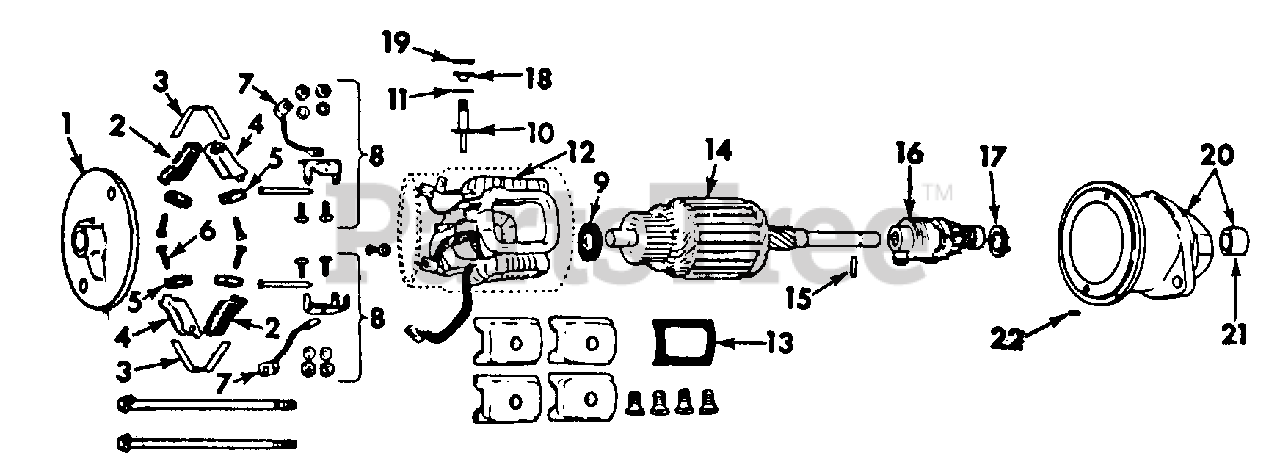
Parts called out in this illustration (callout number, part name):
1	MOTOR ASSY, CRANKING IH-131174-C91
1	FRAME, COMMUTATOR END
2	HOLDER, INSULATED BRUSH
3	SPRING, BRUSH
4	HOLDER, GROUND BRUSH
6	SCREW, COMMUTATOR BRUSH HOLDER
7	LEAD, GROUND BRUSH
8	KIT, BRUSH HOLDER SUPPORT
9	WASHER, COMMUTATOR END BRAKE
10	STUD, TERMINAL
11	WASHER, INSULATED TERMINAL STUD
12	COIL ASSY, FIELD 4 COILS
13	INSULATION, FIELD COIL
15	PIN, ARMATURE SHAFT
16	DRIVE ASSY, MOTOR
17	WASHER, DRIVE END SPACE
18	BUSHING, INSULATED TERMINAL STUD
19	WASHER, INSULATED TERMINAL STUD
20	HOUSING ASSY, DRIVE END
21	BUSHING, DRIVE END HOUSING
22	PIN, DRIVE END DOWEL
